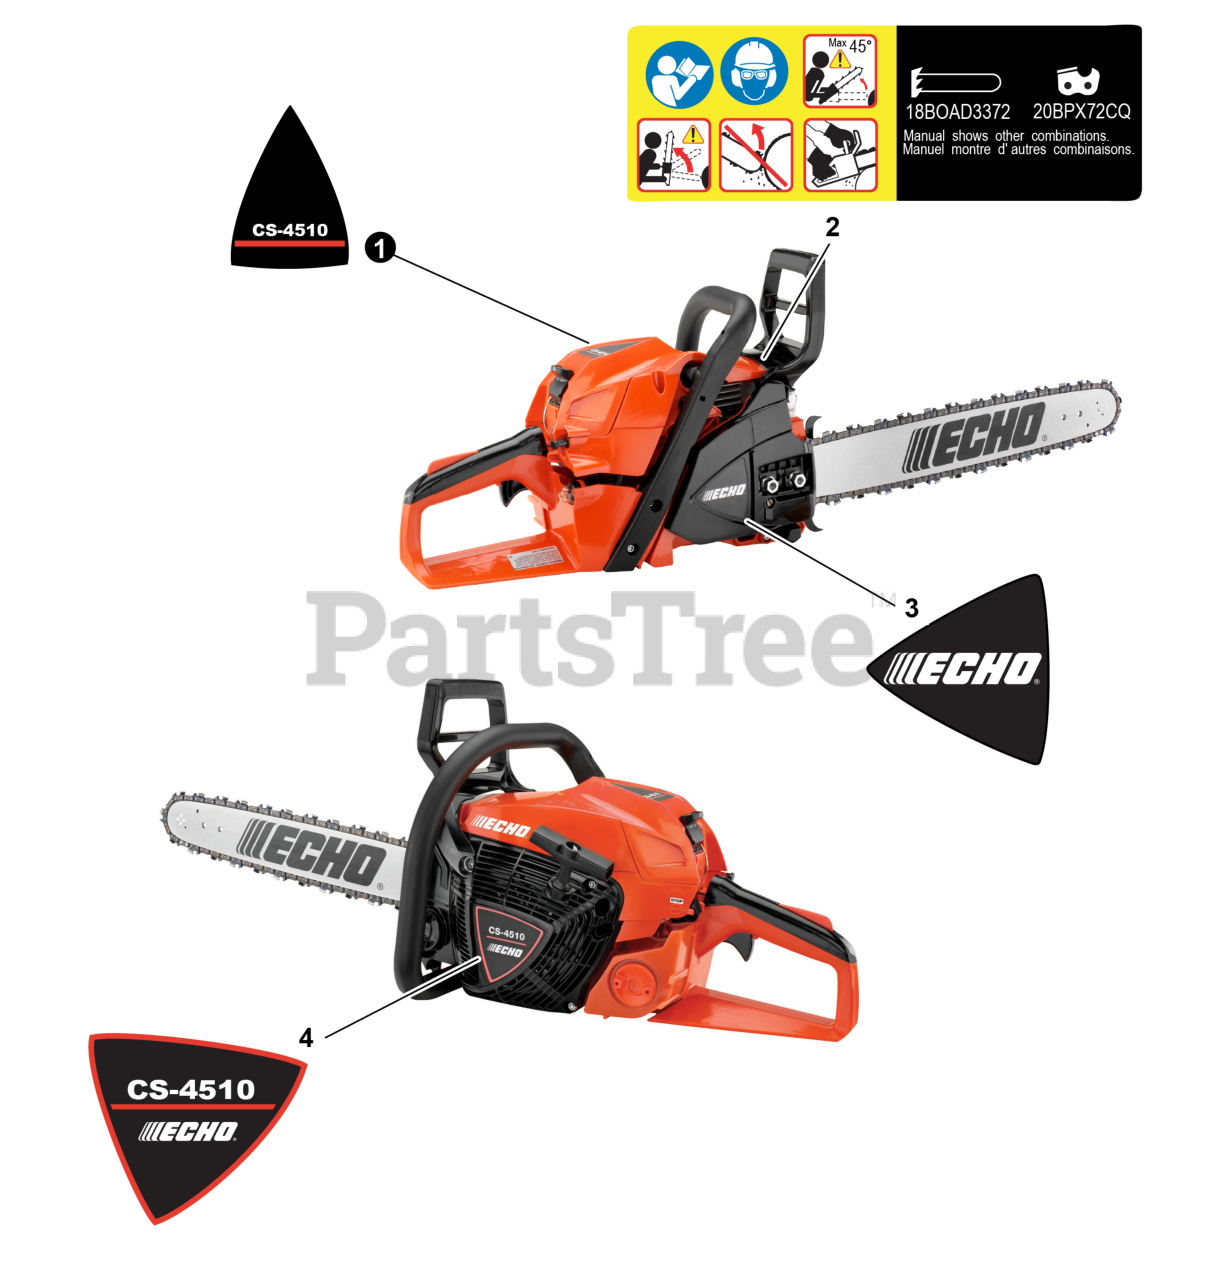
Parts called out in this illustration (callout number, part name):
1	LABEL - MODEL CS-4510
2	LABEL - CAUTION
3	LABEL - ECHO
4	LABEL - MODEL CS-4510
